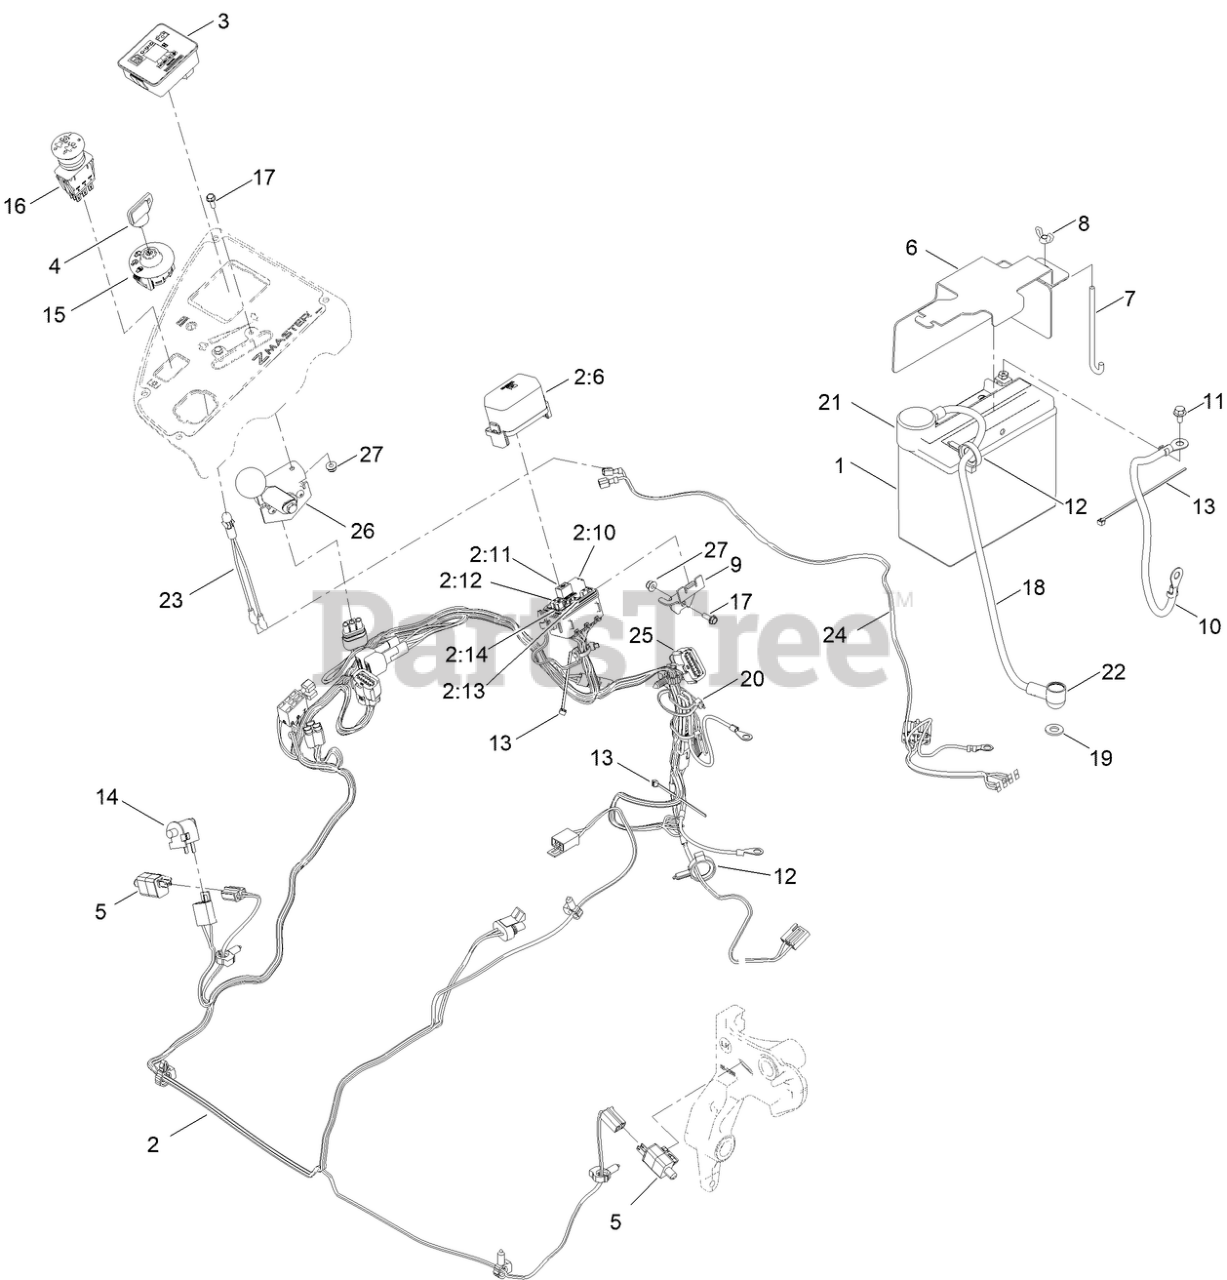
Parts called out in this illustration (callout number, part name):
1	BATTERY-AGM
2	HARNESS-MAIN
2:10	RELAY-MICRO
2:11	RELAY-ENGINE IDLE, 10K
2:12	FUSE-MINI BLADE, 10 AMP
2:13	FUSE-MINI BLADE, 15 AMP
2:14	FUSE-MINI BLADE, 20 AMP
3	FUEL-HOUR METER ASM
4	KEYS-IGNITION (SPARE PAIR)
4	KEY-IGNITION
5	SWITCH
6	BRACKET-HOLDDOWN, BATTERY
7	BOLT-HOLDDOWN
8	WINGNUT
9	PLATE-FUSE HOLDER
10	CABLE-BATTERY, NEGATIVE
11	SCREW-HHF
12	CLAMP-HOSE
13	TIE-CABLE
14	SWITCH-BAIL
15	SWITCH-IGNITION
16	SWITCH, PTO 10A
17	SCREW-HWH
18	CABLE-BATTERY, POSITIVE
19	WASHER-FLAT
20	TIE-CABLE
21	INSULATOR-BATTERY
22	INSULATOR-SOLENOID
23	INDICATOR-LED, RED
24	SCREW-HHF
25	HARNESS-JUMPER
26	THROTTLE CONTROLLER-ETC
27	NUT-HF
